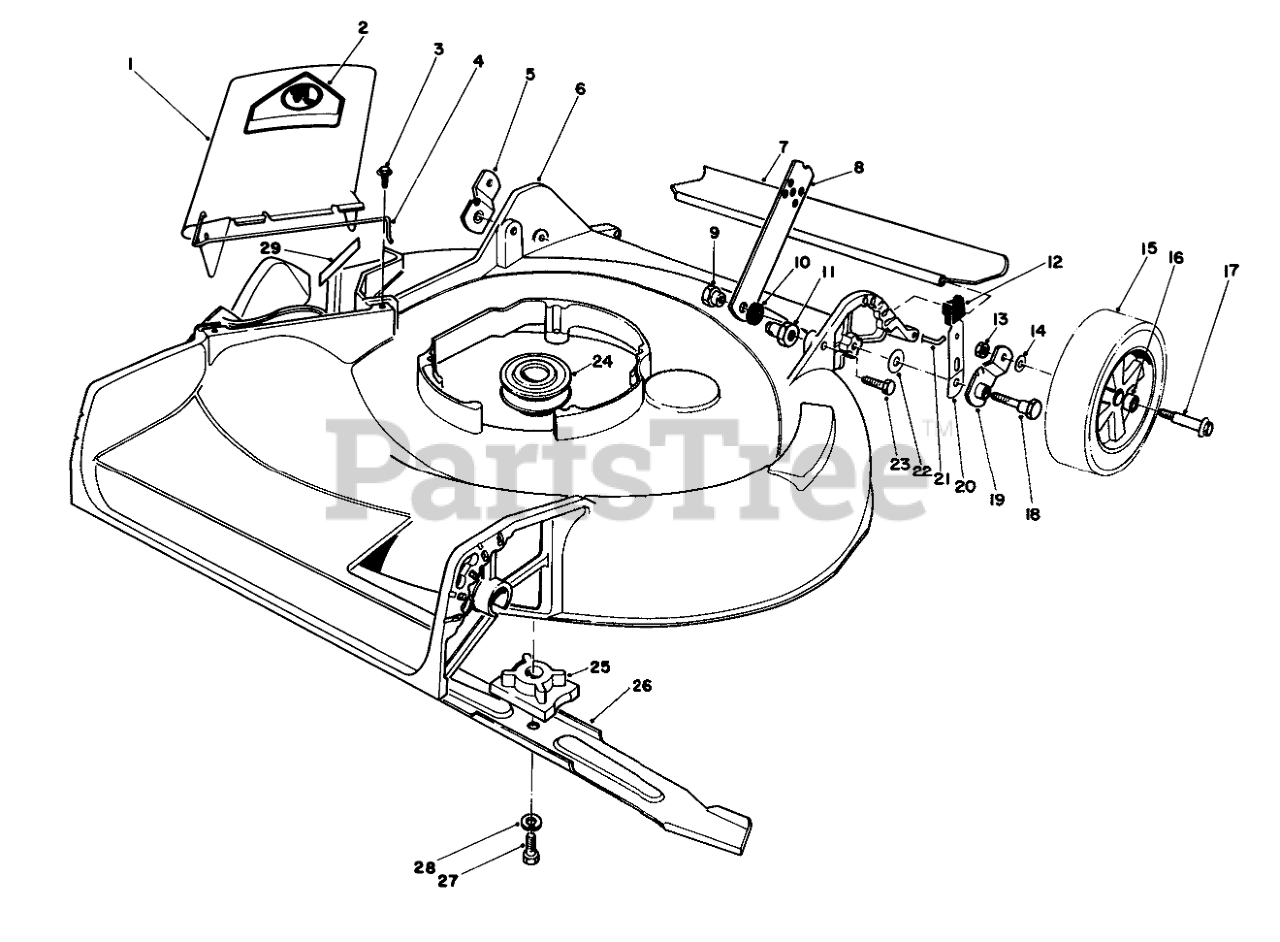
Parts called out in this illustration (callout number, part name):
1	Deflector (Incl. Ref. #2 & 4)
2	DECAL-DANGER
3	SCREW-HWH
4	SPRING HINGE
5	Pivot Arm
6	Housing (Incl. Ref. #29)
7	REAR SAFETY SHIELD 21
8	HANDLE LATCH
9	HANDLE PIVOT NUT
10	SPACER
11	HANDLE PIVOT NUT
12	KNOB-ARM
13	NUT-LOCK
14	WASHER
15	Wheel & Tire Assembly (Incl. Ref. #16 )
16	BUSHING
17	WHEEL BOLT
18	PIVOT SCREW
19	Pivot Arm
20	SPRING ARM ASM
21	SHIELD ROD
22	WASHER-PIVOT
23	SCREW-HH
24	Pulley
25	BLADE RETAINER
26	Blade
27	SCREW-HH
28	WASHER-LOCK
29	Decal-Danger
